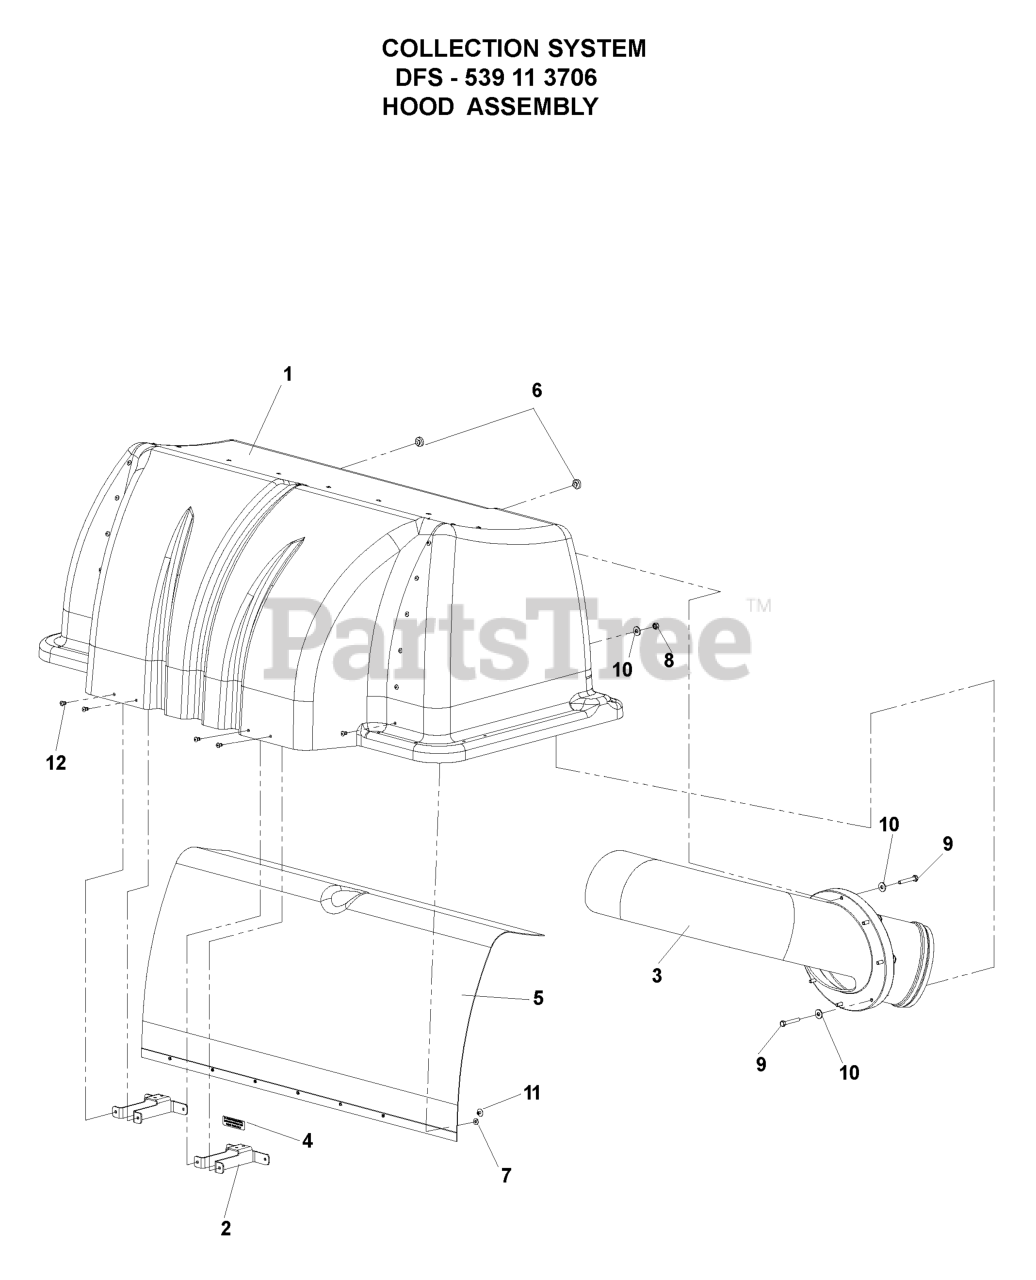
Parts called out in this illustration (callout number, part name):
2	SUPPORT, DRAW LATCH
3	INLET TUBE
4	DECAL, VENTILATION
5	MESH, POLY DIAMOND
6	GROMMET, BUMPER
7	WASHER, #10
8	NUT, 1/4-20, NYLOC
9	HCS, 1/4-20 X 1 3/4, GR5
10	WASHER, 1/4
11	RIVET, 3/16 X 1/4
12	RIVET, 3/16, STAVEX
539113706	Hood Assembly (DFS)
